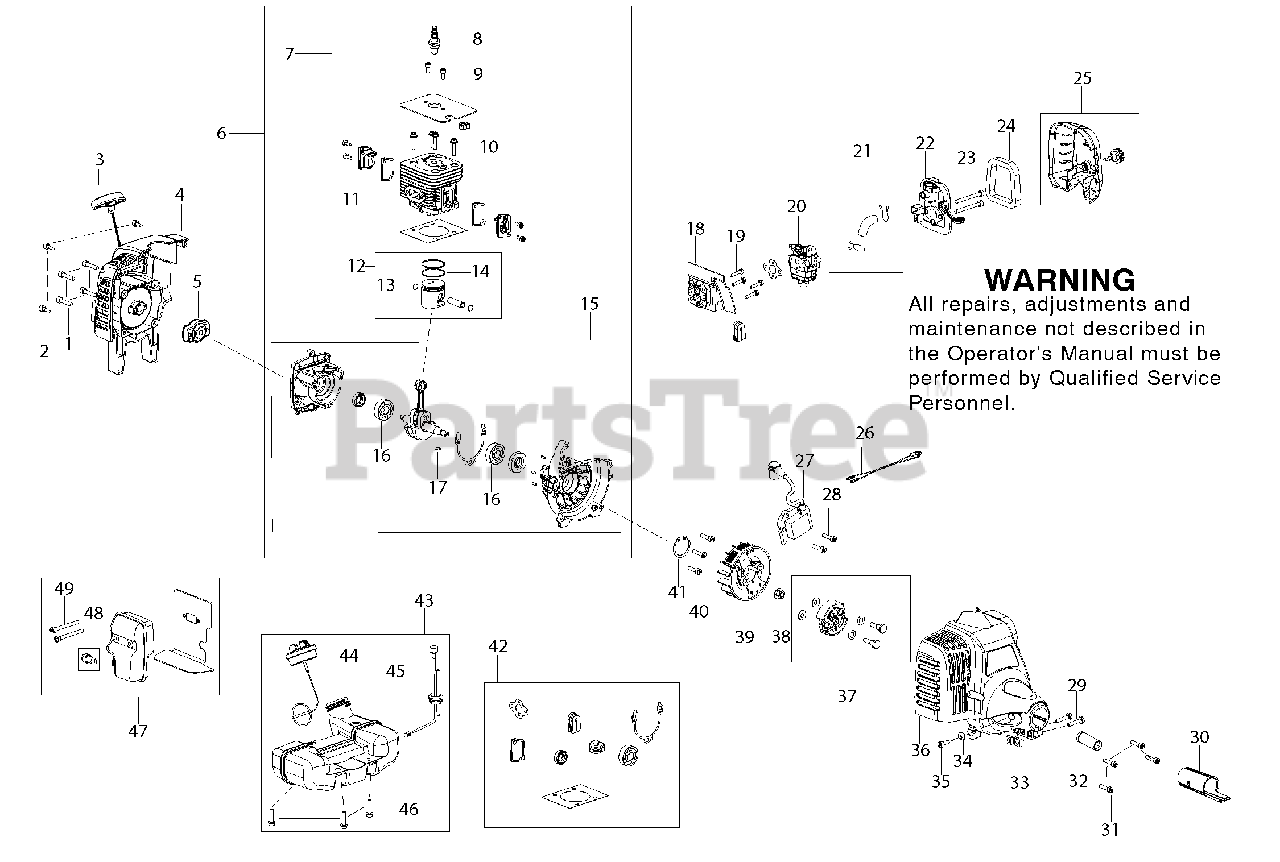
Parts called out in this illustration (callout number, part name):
1	Screw (9sgk-05-12.5, 4-pack)
2	Screw (6sdabb3.5-18)
3	Kit - Rope/Handle
4	Kit - Rear Shroud Assembly
5	Assy. - Pawls (9228-md0107)
6	Kit - Short Block Assembly
7	Kit - Piston & Cylinder
8	Plug - Spark
9	Screw (9sgeb-05-10, 2-pack)
10	Screw (9srcb-05-22,4-pack)
11	Screw (9sgeb-04-10,4-pack)
12	Kit - Piston & Ring
13	Circlip (9131-334501)
14	Ring - Piston (9189-334501)
15	Kit - Crankcase & Crankshaft
16	Bearing (9db-620101, 2-pack)
17	Key (6221-830301)
18	Adaptor - Carburetor
19	Screw - Carb. Adaptor (9skkb05-19, 4-pack)
20	Assembly - Carburetor
21	Kit - Intake Tube
22	Kit - Air Box Base Assembly
23	Screw - Air Box
24	Filter - Air (9183-334501)
25	Kit - Air Box Cover Assembly
26	Assy - Coil Wire (9010-332102)
27	Module - Ignition
28	Screw (9sgeb-05-20, 5-pack)
29	Screw - Nose Clamp
30	Insert - Fan Housing
31	Screw - Fan Hsg to Crankcase
32	Guide - Flexshaft
33	Nut - Square (Nose Clamp)
34	Washer - Lock
35	Screw (9sdabb05-13)
36	Kit - Fan Housing Assembly
37	Kit - Clutch Assembly
38	Nut - Flywheel (9nhc-08)
39	Assembly - Flywheel
40	Screw (9sgeb-05-20)
41	C-Ring (9cb-32)
42	Kit - Gasket
43	Kit - Fuel Tank Assembly
44	Assembly - Fuel Cap
45	Kit - Fuel Line Assembly
46	Screw (9skkby05-18)
47	Kit - Muffler Assembly
48	Kit - Spark Arrestor
49	Screw (9sxmbj05-50, 2-pack)
